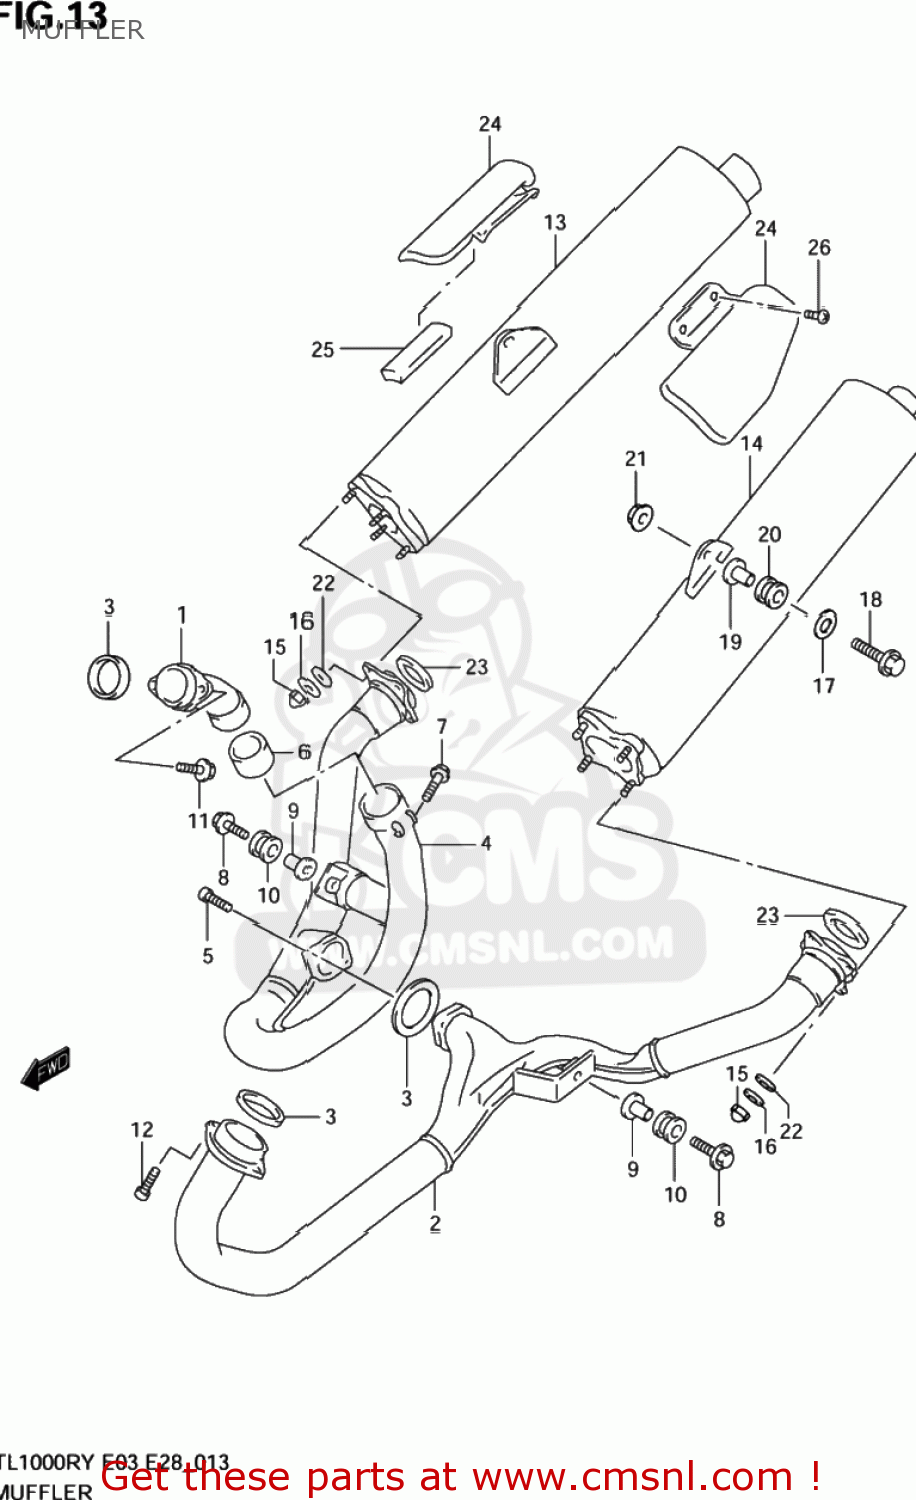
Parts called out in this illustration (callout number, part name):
1	PIPE,EXHAUST,R
2	PIPE,EXHAUST,L
3	GASKET,EXHAUST PIPE (NAS)
4	PIPE,EXHAUST JOINT,R
5	BOLT,EXH MANF
6	CONNECTOR,EXHAUST,R
7	BOLT
8	BOLT 8X45
9	SPACER(8.6X12X24.2)
10	CUSHION
11	BOLT
12	BOLT
13	BODY,MUFFLER,R
14	BODY,MUFFLER,L
15	NUT
16	WASHER(8.5X18X1.6)
17	WASHER (8.5X33X1.6)
18	BOLT
19	SPACER(8.6X12X27.1)
20	CUSHION
21	NUT
22	O RING(D:1.9,ID:7.8)
23	GASKET,MUFFLER JOINT (NAS)
24	PROTECTOR,MUFFLER,R
25	CUSHION,MUFFLER COVERER
26	SCREW(6X12)
